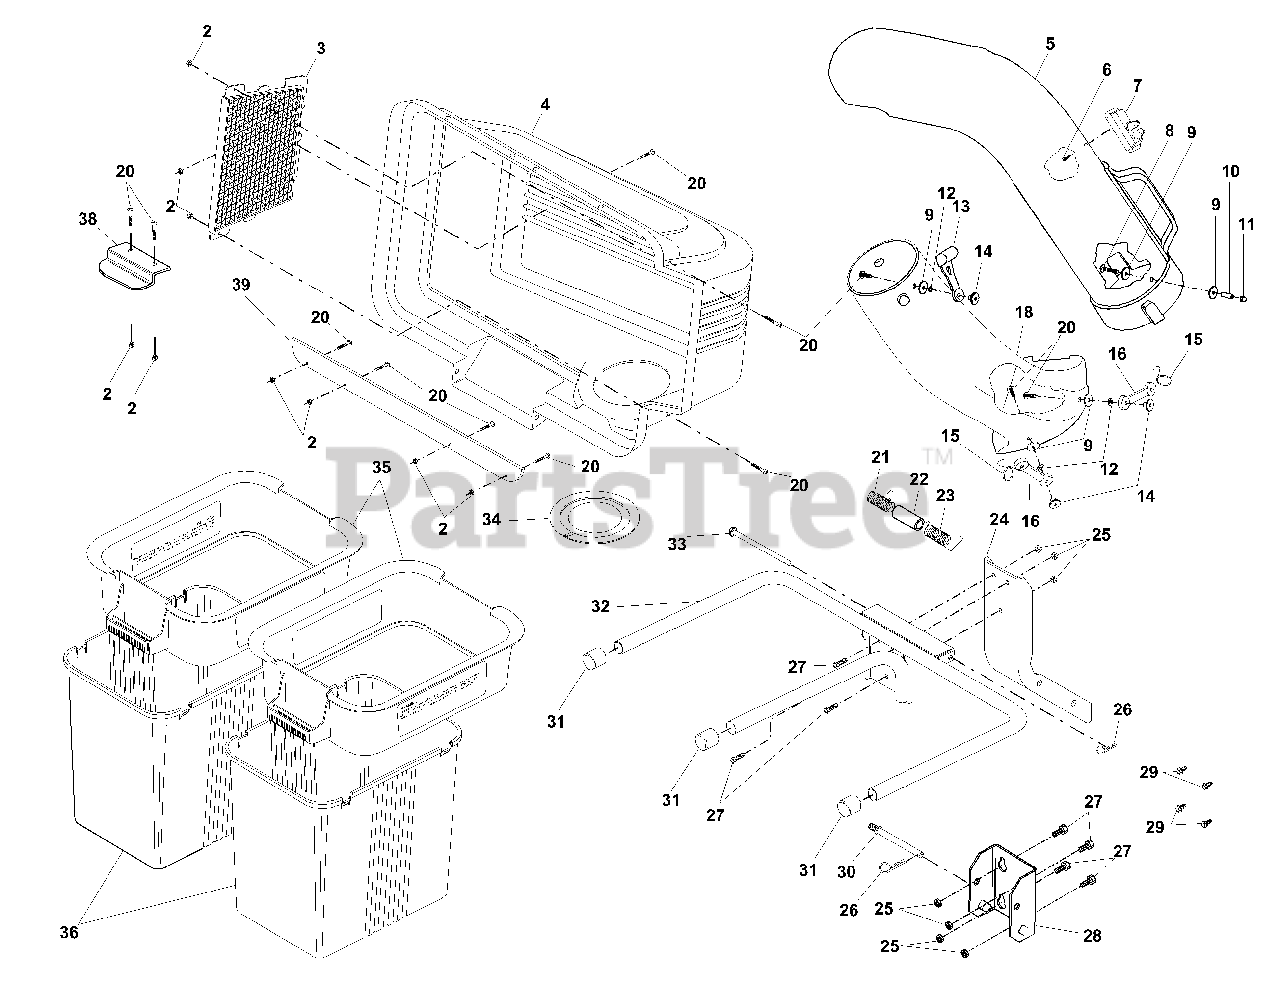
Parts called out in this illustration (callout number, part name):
2	Nut, Crownlock #10-24
3	Screen, Cover
4	Cover Asm.
5	Chute, Upper
6	Screw, Special #10- 14x1/2
7	Dump Bag Indicator
8	Screw, #10-24 x 1- 1/8
9	Washer 3/16 x 3/4x16 Ga.
10	Spacer, Split
11	Nut, Acorn #10-24
12	Washer, lock
13	Latch, Chute
14	Nut, Weld
15	Latch, Hook
16	Rubber, Latch
18	Chute, Lower
20	Screw #10-24 x 5/8
21	Spring, Cover L. H. (black)
22	Spacer, Cover
23	Spring, Cover R. H. (gray)
24	Post, Support
25	Locknut 5/16 x 18
26	Spring, Retainer
27	Bolt, Hex 5/16-18 x 3/4
28	Bracket, Mounting
29	Shoulder Bolt
30	Pin, Support Post
31	Plug, Tubing End
32	Bagger, Frame
33	Pin, Hinge
34	Gasket, Cover
35	Container, Top
36	Container, Bottom
38	Latch Handle, Cover
39	Strip, Reinforcement
